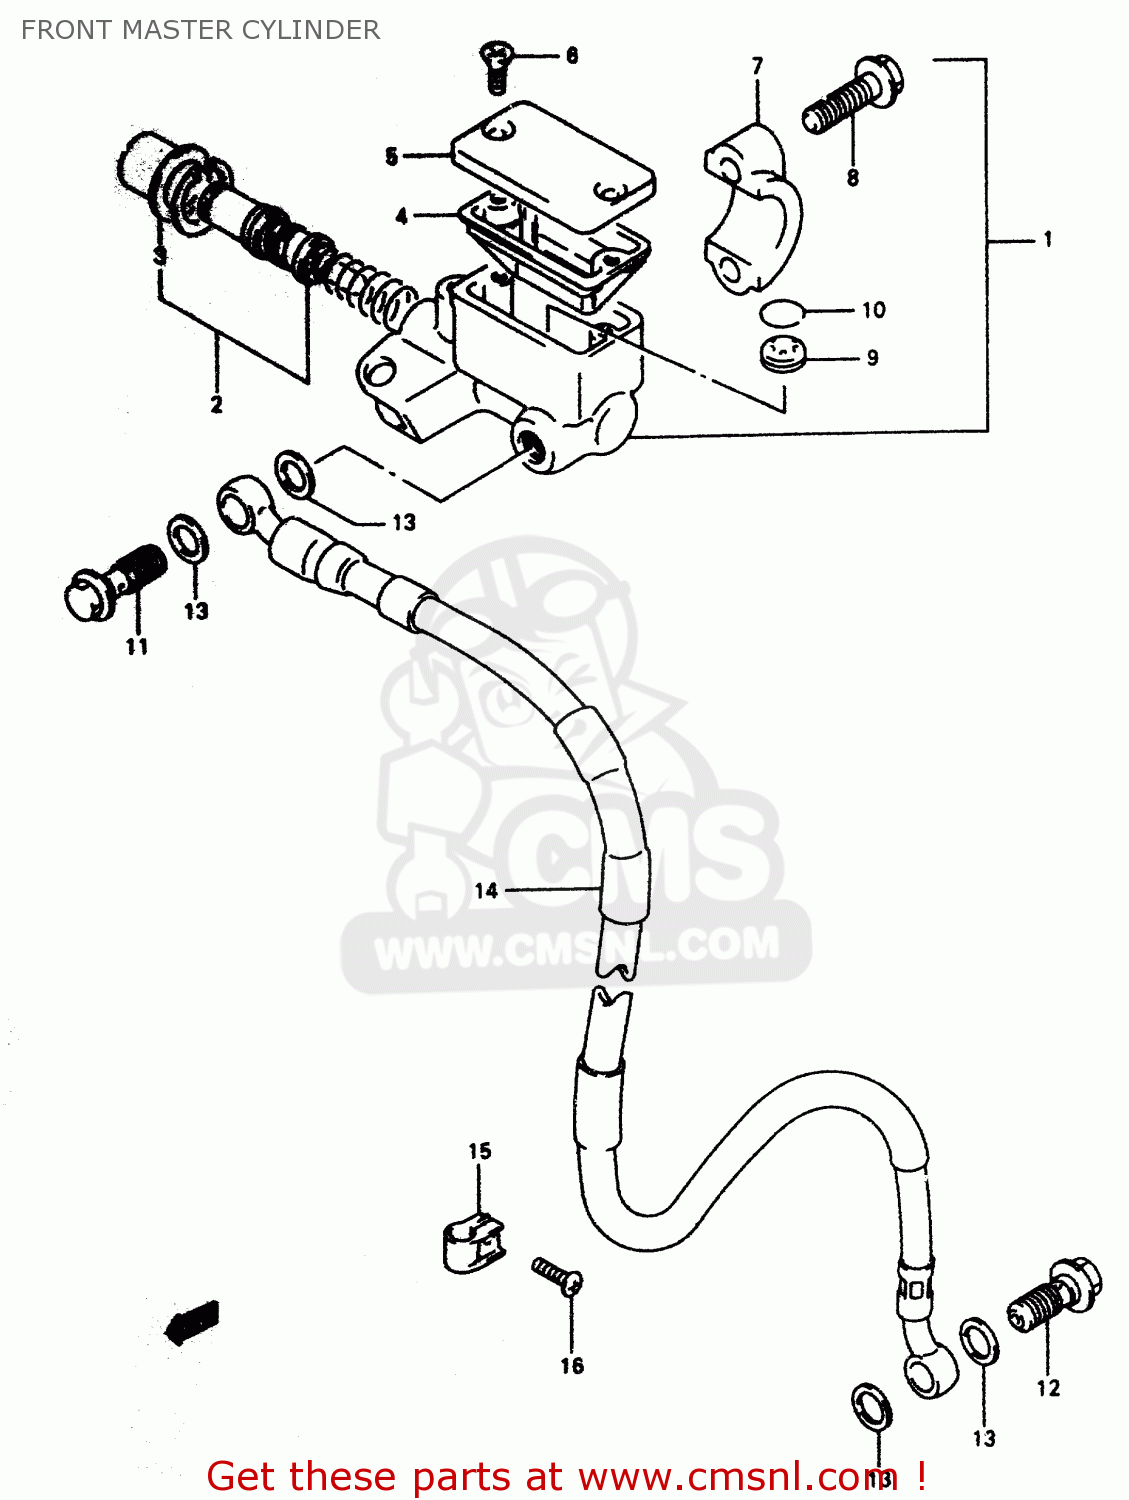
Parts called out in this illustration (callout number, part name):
1	CYLINDER ASSY,FR MASTER
2	PISTON & CUP SET
3	BOOT
4	DIAPHRAGM
5	CAP
6	SCREW
7	HOLDER
8	BOLT
9	SEPARATOR
10	RING
11	BOLT UNION
12	BOLT UNION
13	WASHER(10X15X1.5)
14	HOSE,FR BRAKE
15	CLAMP,BRAKE HOSE
16	SCREW
